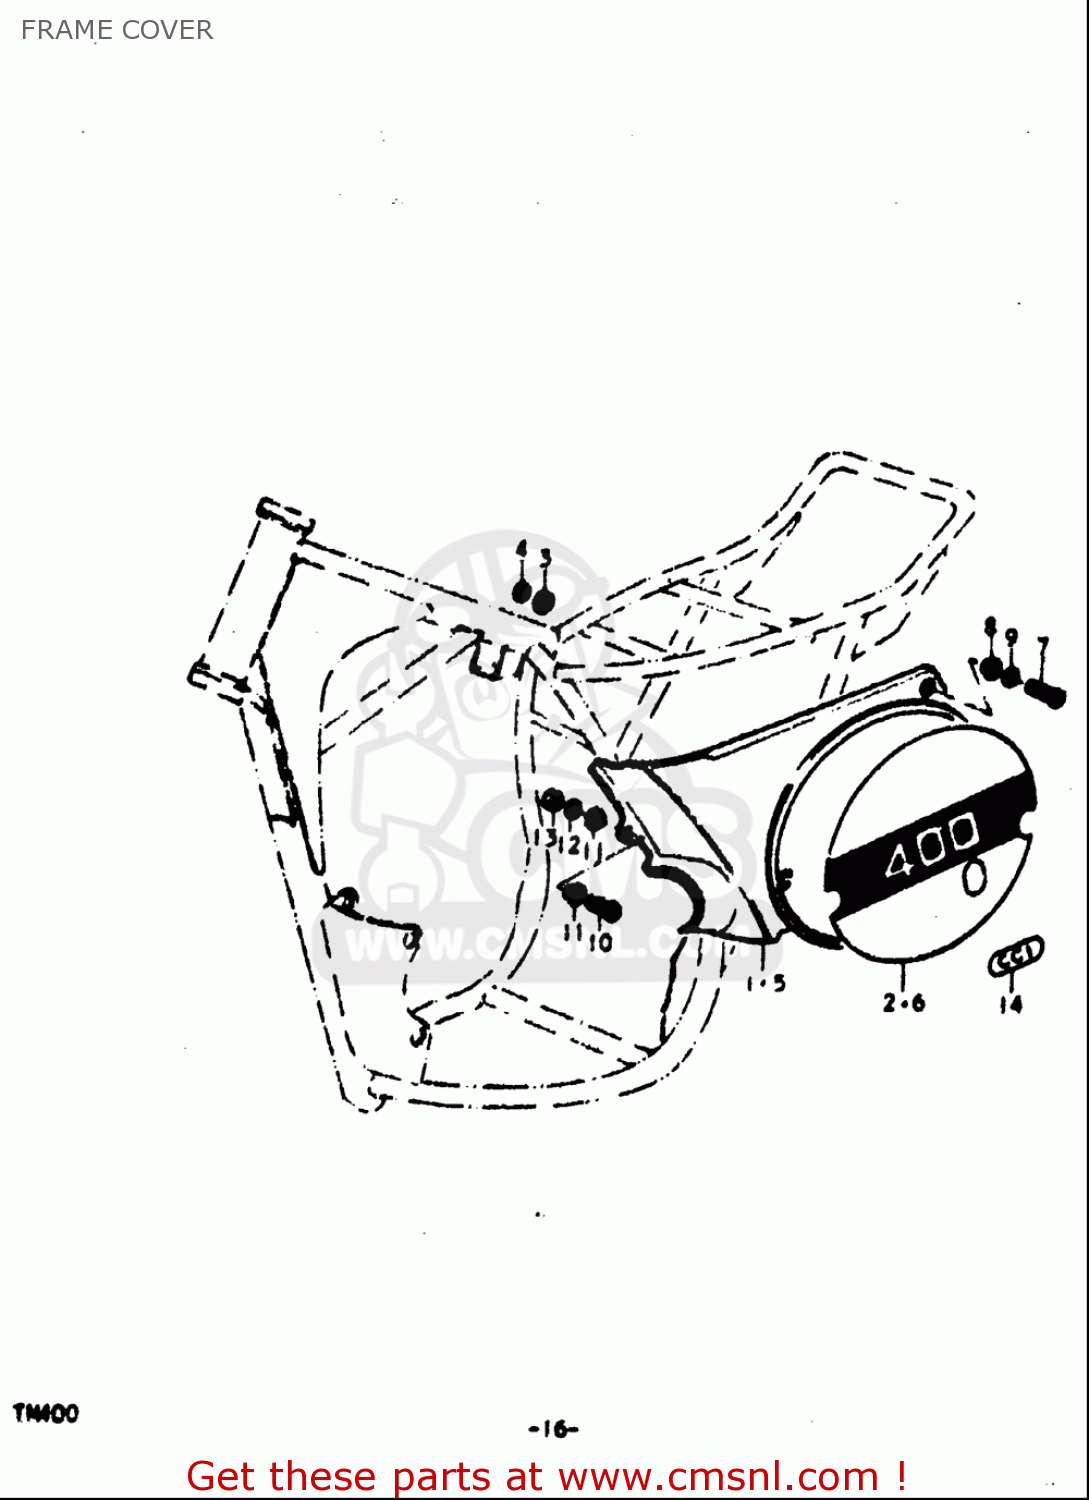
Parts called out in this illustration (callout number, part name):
3	WASHER
4	WASHER,LOCK
7	SCREW
8	WASHER
9	WASHER,LOCK
10	SCREW
11	WASHER
12	WASHER,LOCK
13	NUT
14	EMBLEM,CCIS
